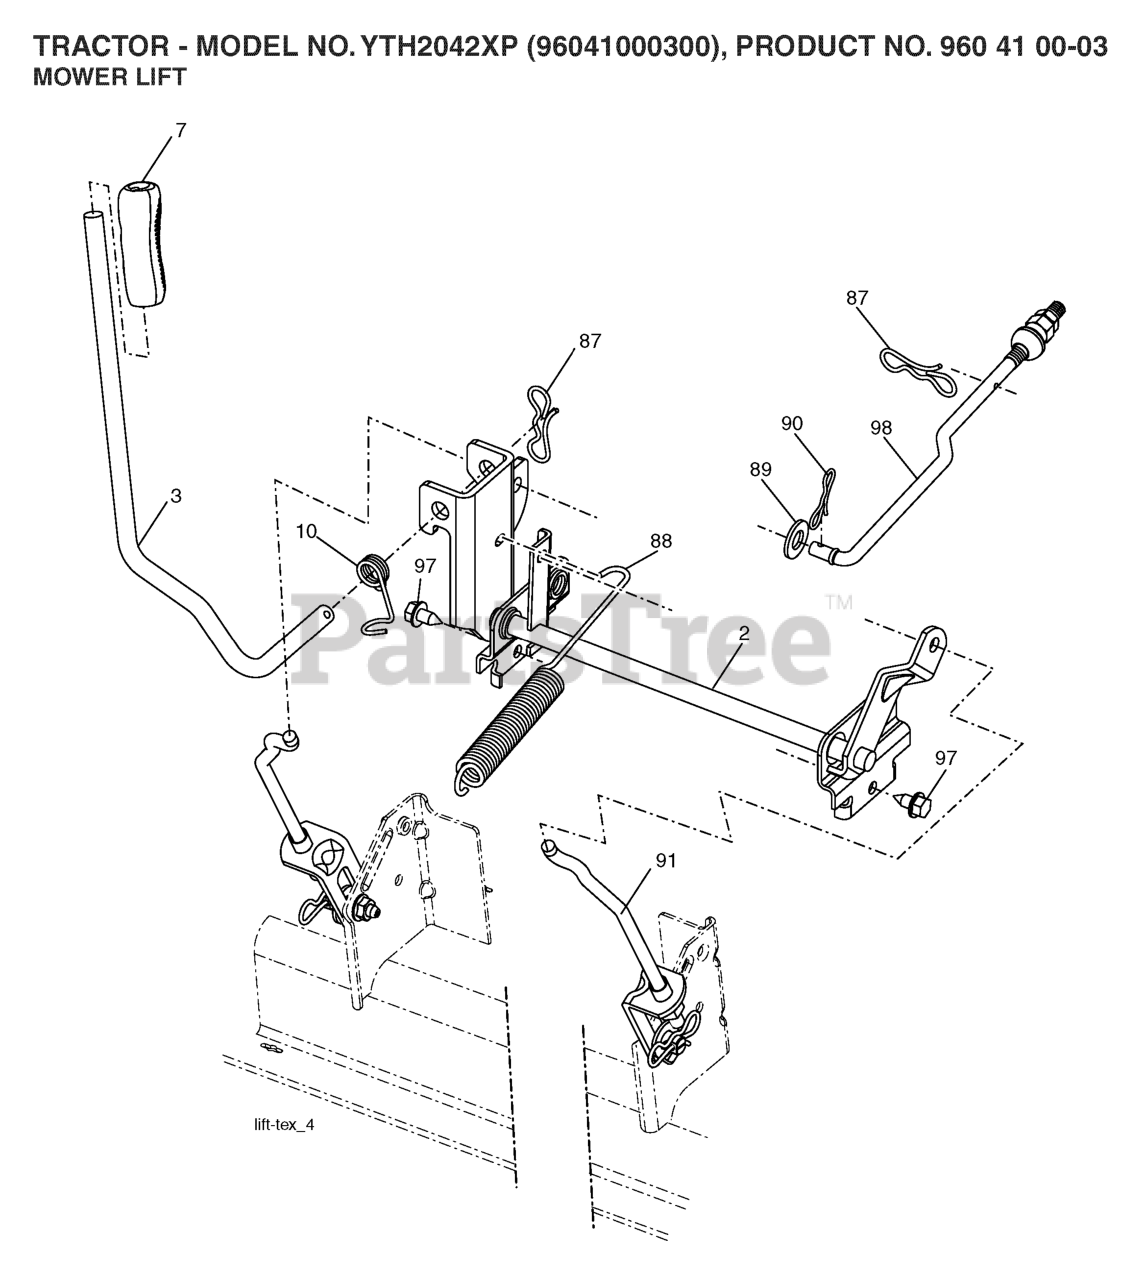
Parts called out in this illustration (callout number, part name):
2	SHAFT.ASM.LIFT.CROSS.H
3	LEVER.LIFT.HANDLE.GT
7	GRIP.LEVER.5625.ID
10	SPRING.TORSION.LIFT.HANDLE
87	PIN.COTTER.7/16.BOW TI.
88	SPRING.LIFT.ASSIST.GT2
89	WASHER.CLEAR.ZINC
90	PIN.COTTER.5/16.BOW TI
91	LINK.ASM.LIFT.REAR
97	SCREW 3/8-16X3/4
98	LINK.ASM.SUSP.FRONT.MW
